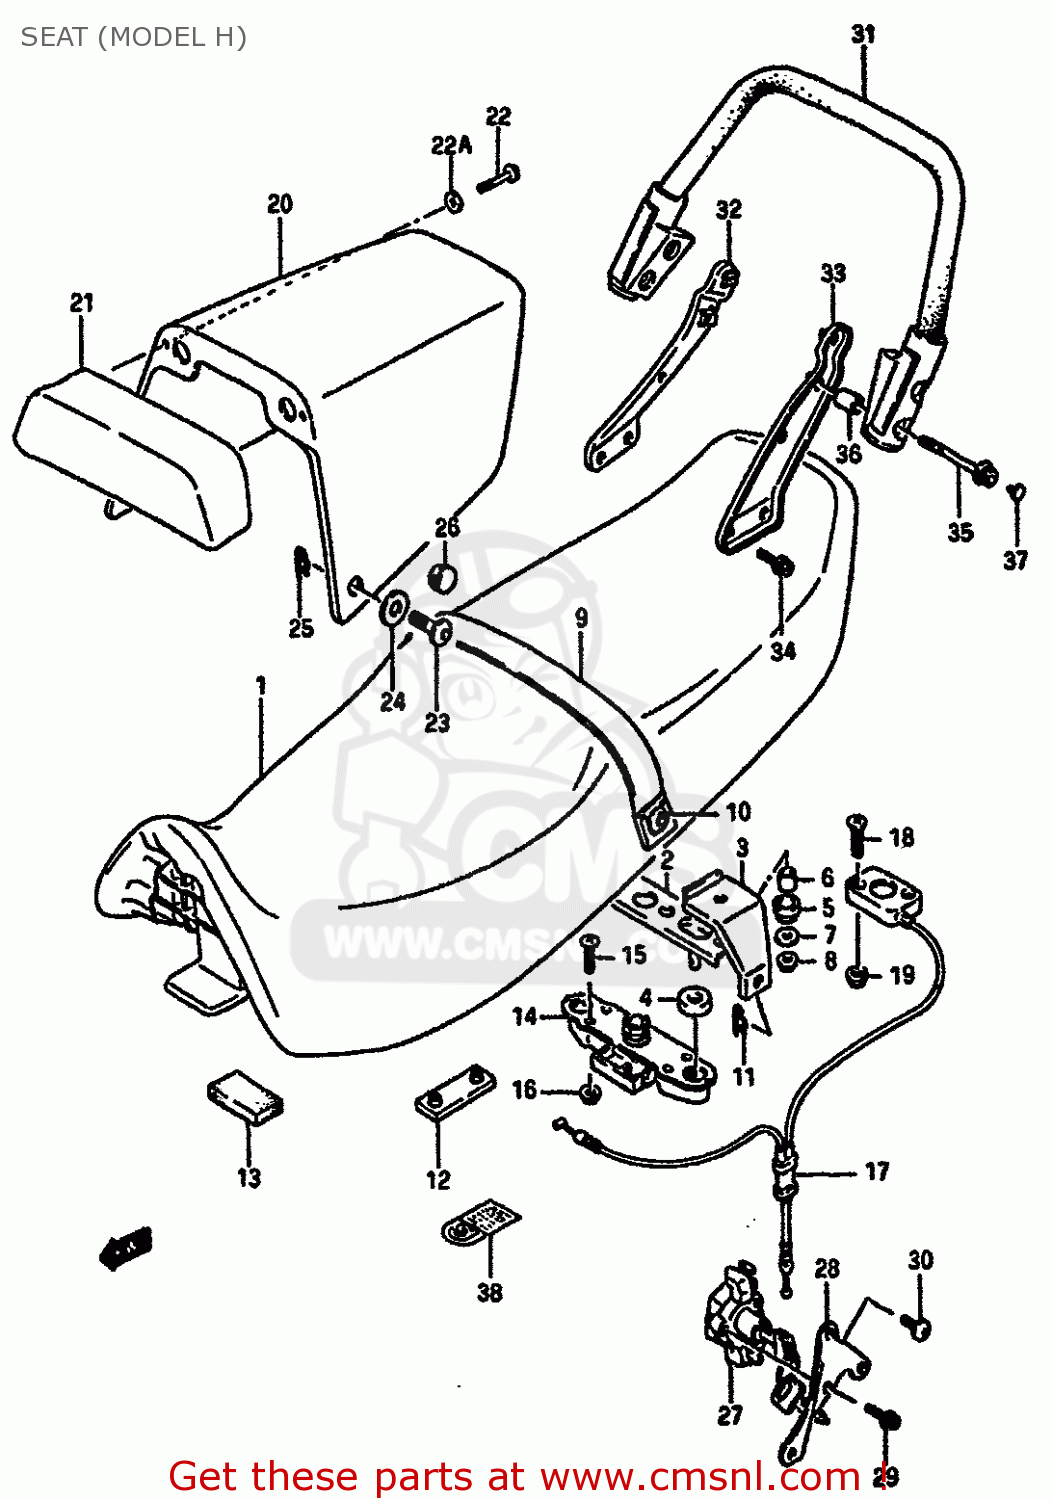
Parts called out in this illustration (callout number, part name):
1	SEAT ASSEMBLY
2	STRIKER,SEAT LOCK
3	PLATE,SEAT GRIP BAND
4	CUSHION
5	CUSHION
6	SPACER
7	WASHER
8	NUT
9	BAND,SEAT
10	BOLT
11	CLIP
12	CUSHION
13	CUSHION
14	LOCK ASSY,SEAT STRIKER
15	SCREW
16	NUT
17	BRACKET,SEAT SUPPORT RR
18	SCREW
19	NUT
20	BOX SET,SEAT TAIL
21	BACKREST,SEAT
22	SCREW, CENTER
22A	WASHER (6.5X18X1.6)
23	BOLT
24	WASHER(10X25X3.2)
25	CLIP
26	CAP,SEAT TAIL COVER
27	LOCK SET
28	BRACKET,SEAT LOCK
29	SCREW 6X12
30	PLUG ,6X20
31	HANDLE,PILLION RIDER
32	PLATE,PILLION HANDLE,R
33	PLATE COMP,PILLION HANDLE
34	BOLT
35	BOLT
36	SPACER (8.6X13.8X21.5)
37	CAP(OD:10)
38	LABEL,ASBESTOS WARNING
